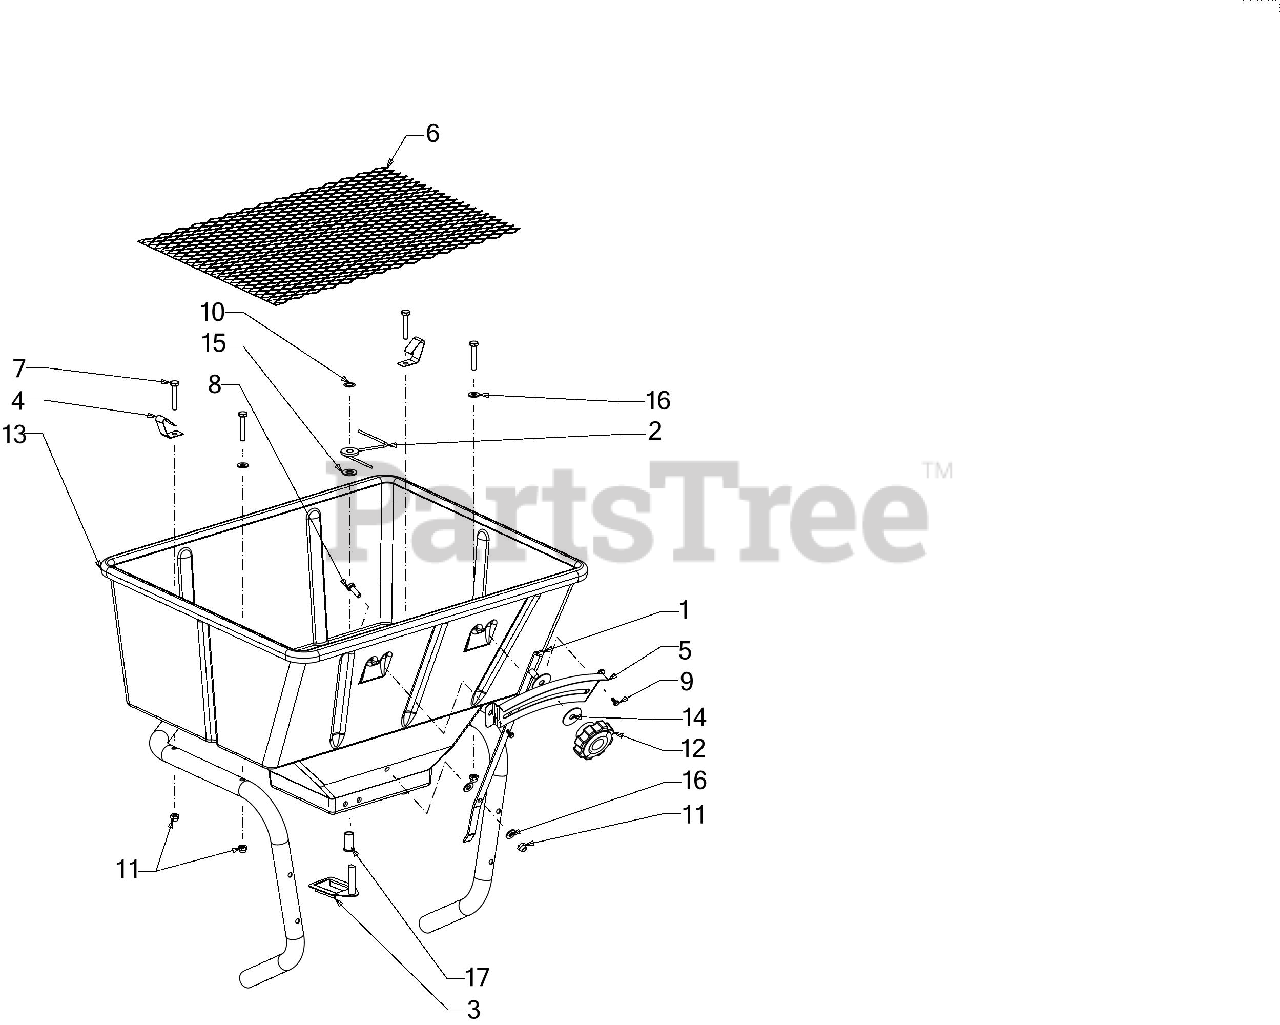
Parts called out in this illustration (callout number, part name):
1	CONTROL RATE ARM
2	AGITATOR ARM ASSEMBLY
3	AGITATOR CAM
4	SCREEN CLIP
5	CONTROL PLATE RATE
7	BOLT- 1/4-20X1.50
8	BOLT-1/4-20X.750
9	BOLT:FLANGE - 8-18X.375
10	RETAINER SPRING CLIP
11	NYLOCK NUT 1/4-20
12	KNOB-5/16-18
13	HOPPER-#80
14	WASHER .355X1.25X.048THK
15	NYLON WASHER
17	AGITATOR BEARING
